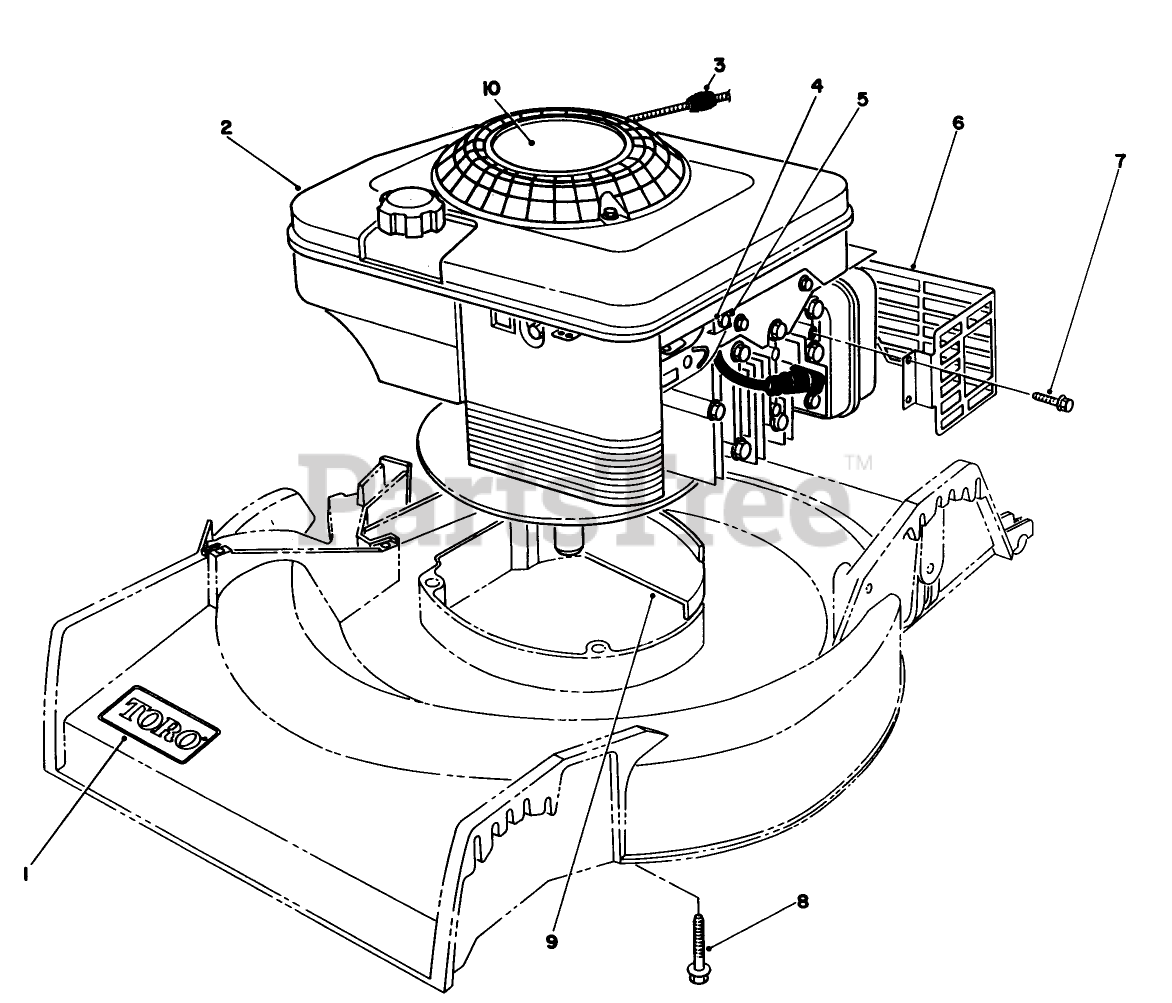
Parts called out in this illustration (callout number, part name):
1	DECAL
2	Engine
3	STOP-ROPE
4	CLAMP-CASING
8	THD FORM SCREW
9	HOUSING CAP
